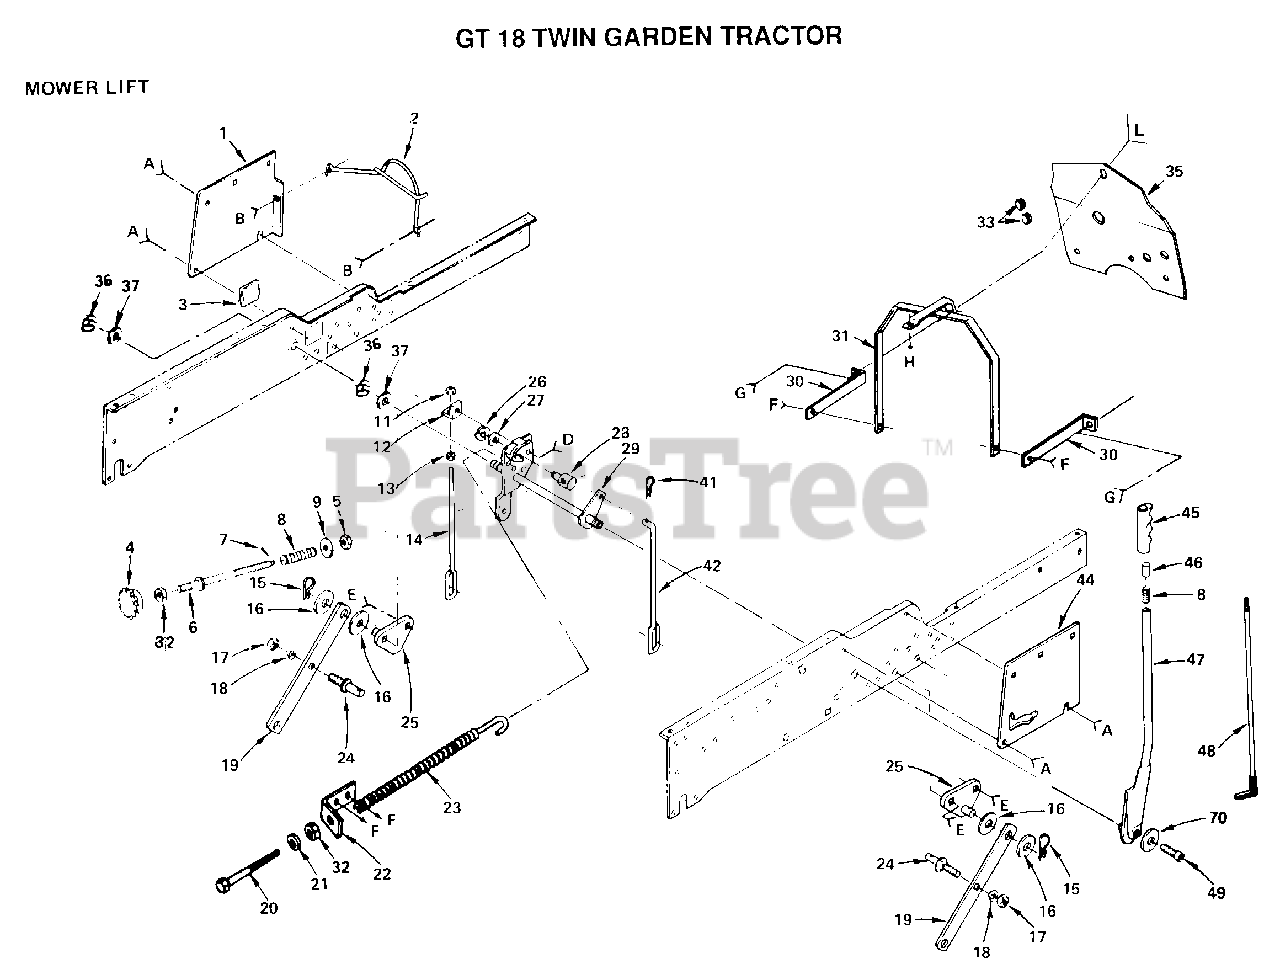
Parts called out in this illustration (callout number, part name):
3	COVER ACCESS
4	HDLE ADJ LIFT
5	NUT T
6	ROD ADJ. T
8	SPRING T
9	WASHER
11	NUT
12	BRACKET T
13	NUT.HEX.3/8-16UNC
14	LINK-LIFT MOW T
15	SPRING H
17	NUT
18	LOCKWASHER
19	SUSPENSION ARM GT
20	BOLT-ADJ SPRING T
21	WASHER
24	PIVOT STUD GT
25	SUSP BRACKET T
26	KLIP RING
27	WASHER
28	TRUNION LT
30	BRACKET T
32	NUT
35	"SHIELD HEAT, BASE"
36	E-RING
37	WASHER
42	LIFT LINK RH T
45	GRIP
48	LEVER ROD LT
70	LOCKWASHER
